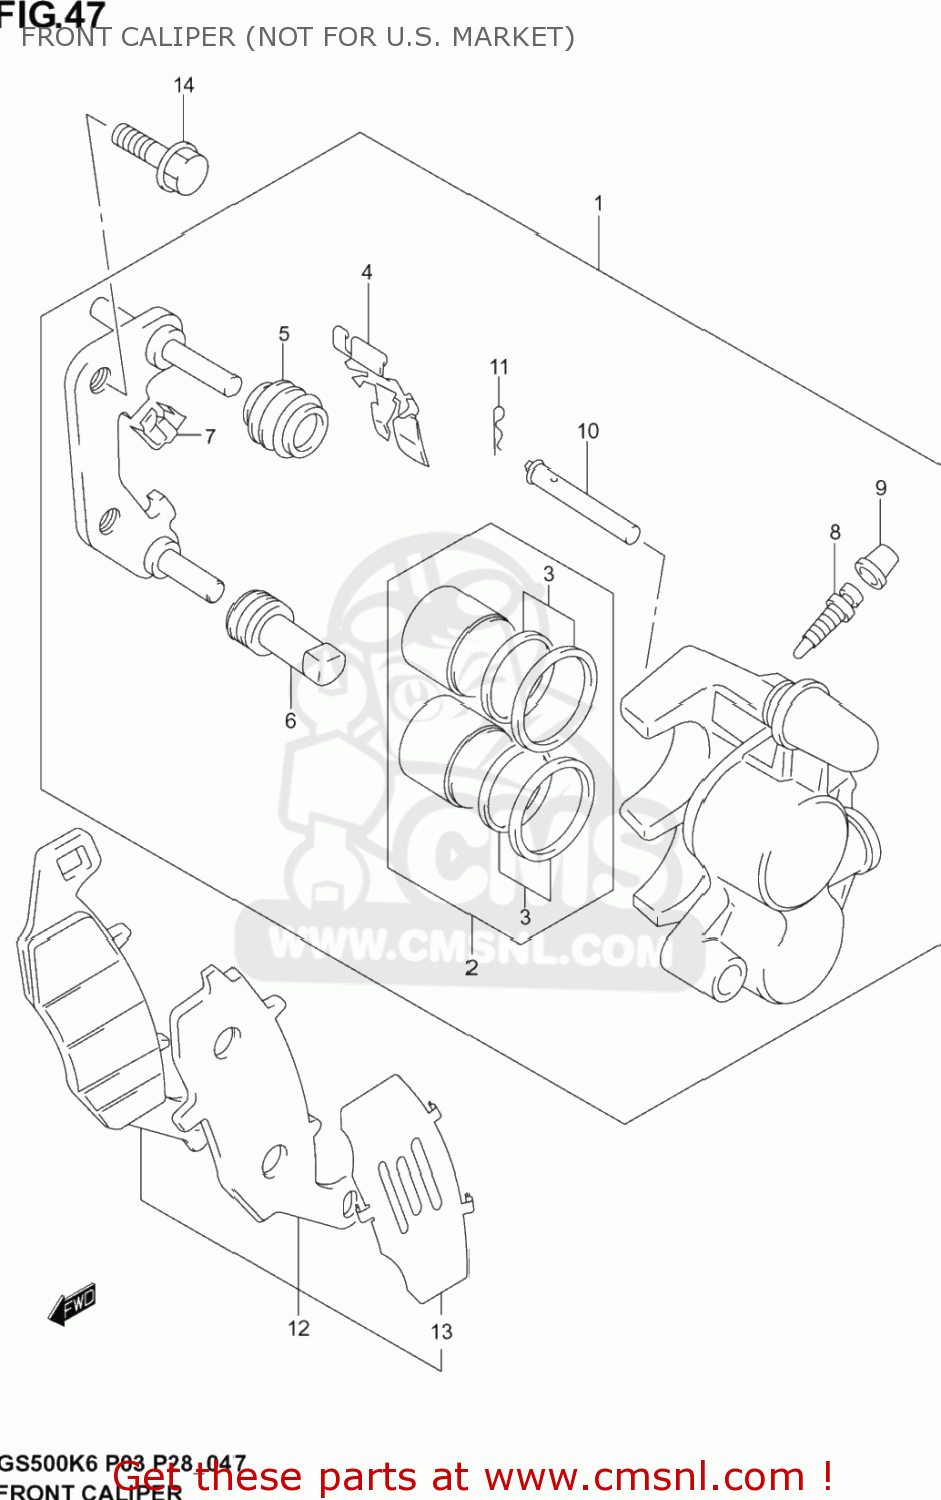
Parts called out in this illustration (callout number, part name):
1	CALIPER ASSY, FRONT RH
2	PISTON SET
3	SEAL SET,PISTON
4	SPRING,PAD,R
5	BOOT,AXLE
6	INSULATOR,AXLE
7	GUIDE,PAD
8	BLEEDER
9	CAP,BLEEDER PLUG
10	PIN,PAD
11	CLIP,PAD PIN
12	PAD & SHIM SET (NAS)
13	SHIM,PAD
14	BOLT
